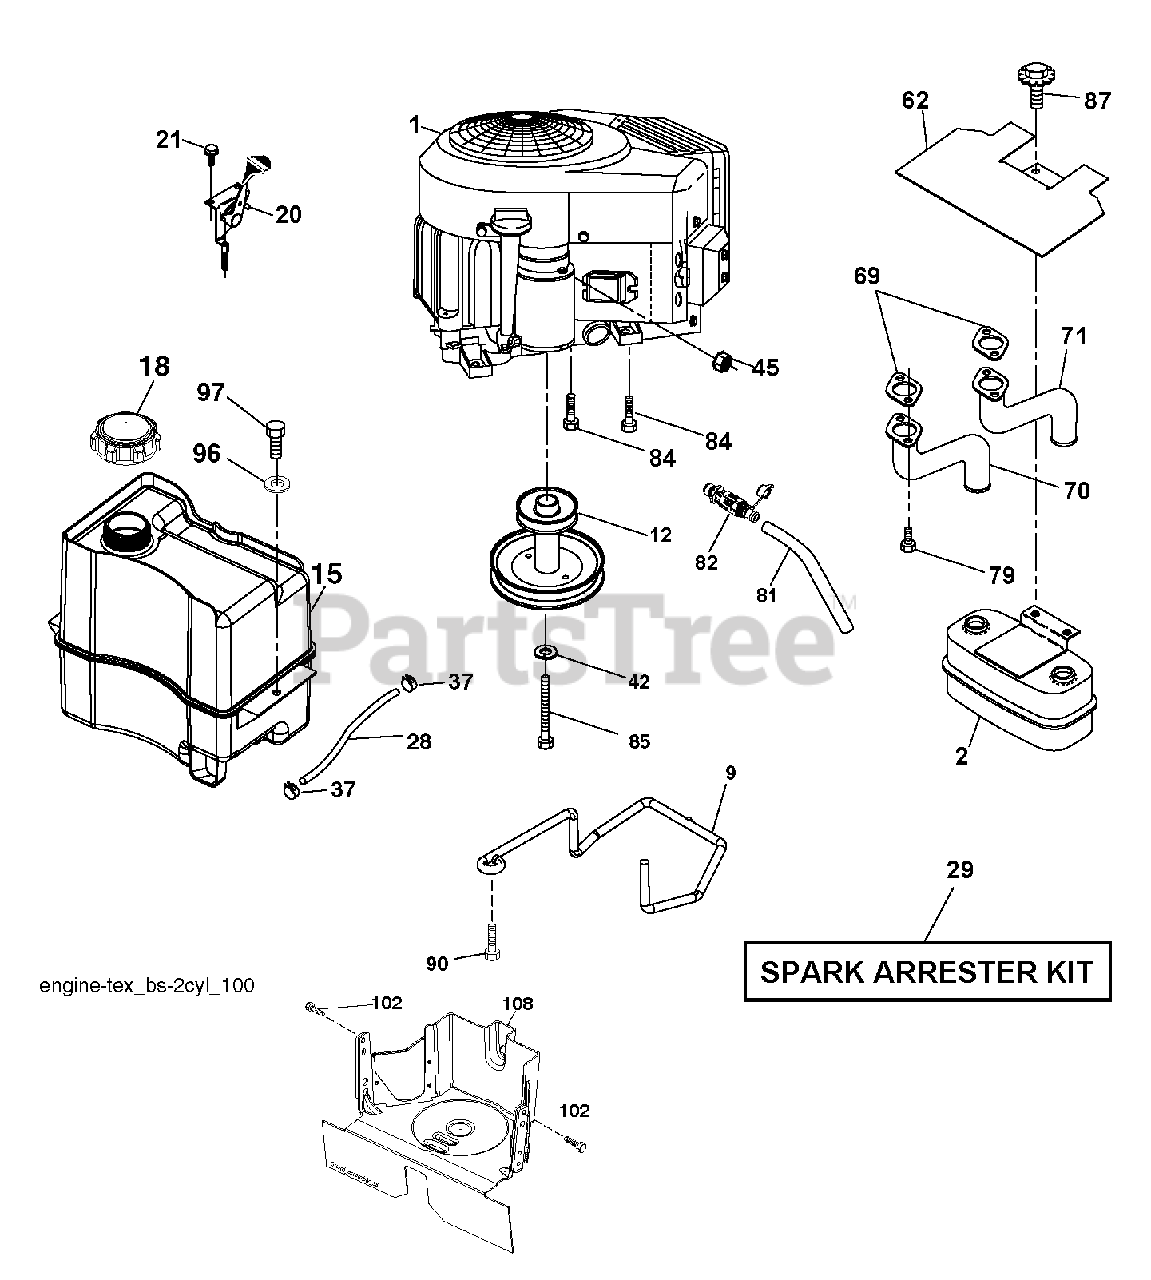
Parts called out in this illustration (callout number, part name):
2	MUFFLER.ASM.TWN.EXTNDED.DFLCTR
9	KEEPER BELT ENGINE
12	PULLY ENGINE
15	TANK.ASSEMBL.2.5GAL.NON-EPA
18	CAP.ASM.FUEL.2.25"TOP.TURN
20	CONTROL.TH/CK.COBRA.B&S.TWN.
21	SCREW.#10 X 0.750.BOS
28	LINE.FUEL.20
29	KIT.SPARK ARRESTOR 794945 B&S
37	HOSE CLAMP
42	LOCKWASHER
45	NUT
62	SHIELD.HEAT.MUFFLER
69	GASKET.MUFFLER
70	EXHAUST.TUBE.LH.BS/TWIN
71	EXHAUST.TUBE.RH.B&S.TWIN.INTEK
79	SCREW.SOCKET.HEAD.5/16-18
81	TUBE, DRAIN OIL ASM.
82	VALUE.OIL.DRAIN
84	SCREW.3/8-16
85	BOLT HEX 7/16-20X4-1/4"
87	BOLT, 5/16-18 X 1 3/4
90	SCREW 3/8-16X1
97	SCREW HEXWSHR 1/4-20X3/4
102	SCREW 5/16-18X1
108	COVER PULLEY
